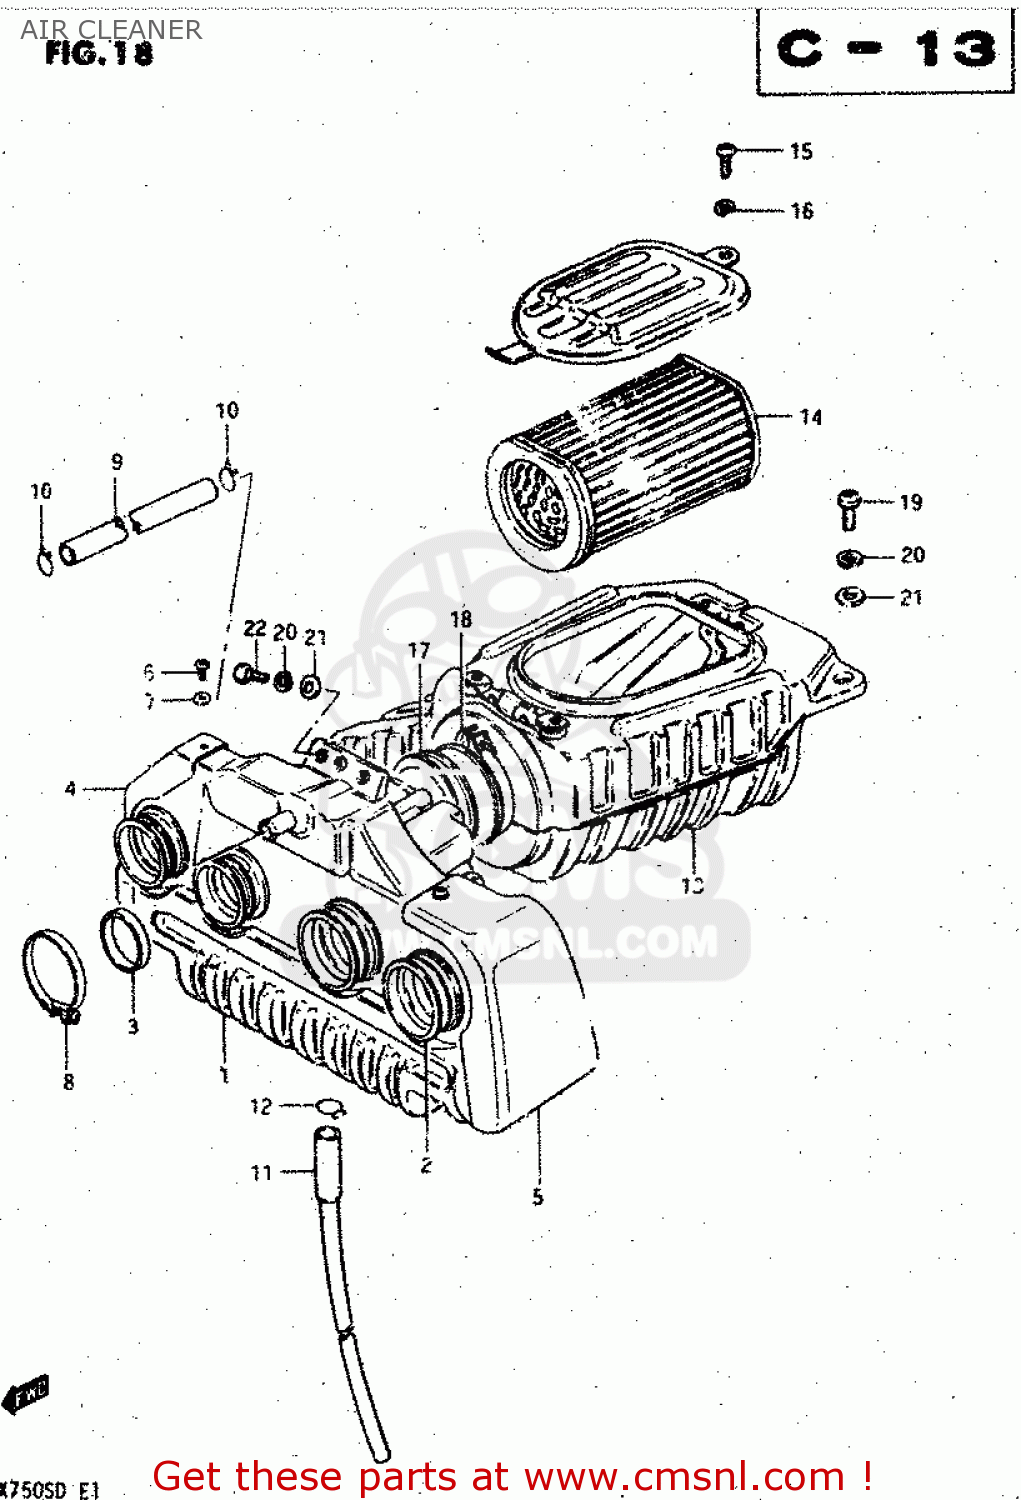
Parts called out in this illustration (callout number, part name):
1	CASE COMP,AIR CLEANER
2	TUBE,OUTLET
3	RING,CARBURETOR AIR INLET HOSE
4	COVER,AIR CLEA
5	COVER
6	SCREW 4X6
7	WASHER
8	CLAMP
9	TUBE,BREATHER
10	CLIP
11	DRAIN TUBE
12	CLIP
13	CLEANER SET,AIR,REAR
14	FILTER,AIR CLEANER
15	SCREW
16	LOCK WASHER
17	HOSE,AIR CLEANER
18	BAND
19	SCREW
20	LOCK WASHER
21	WASHER 6MM
22	BOLT
